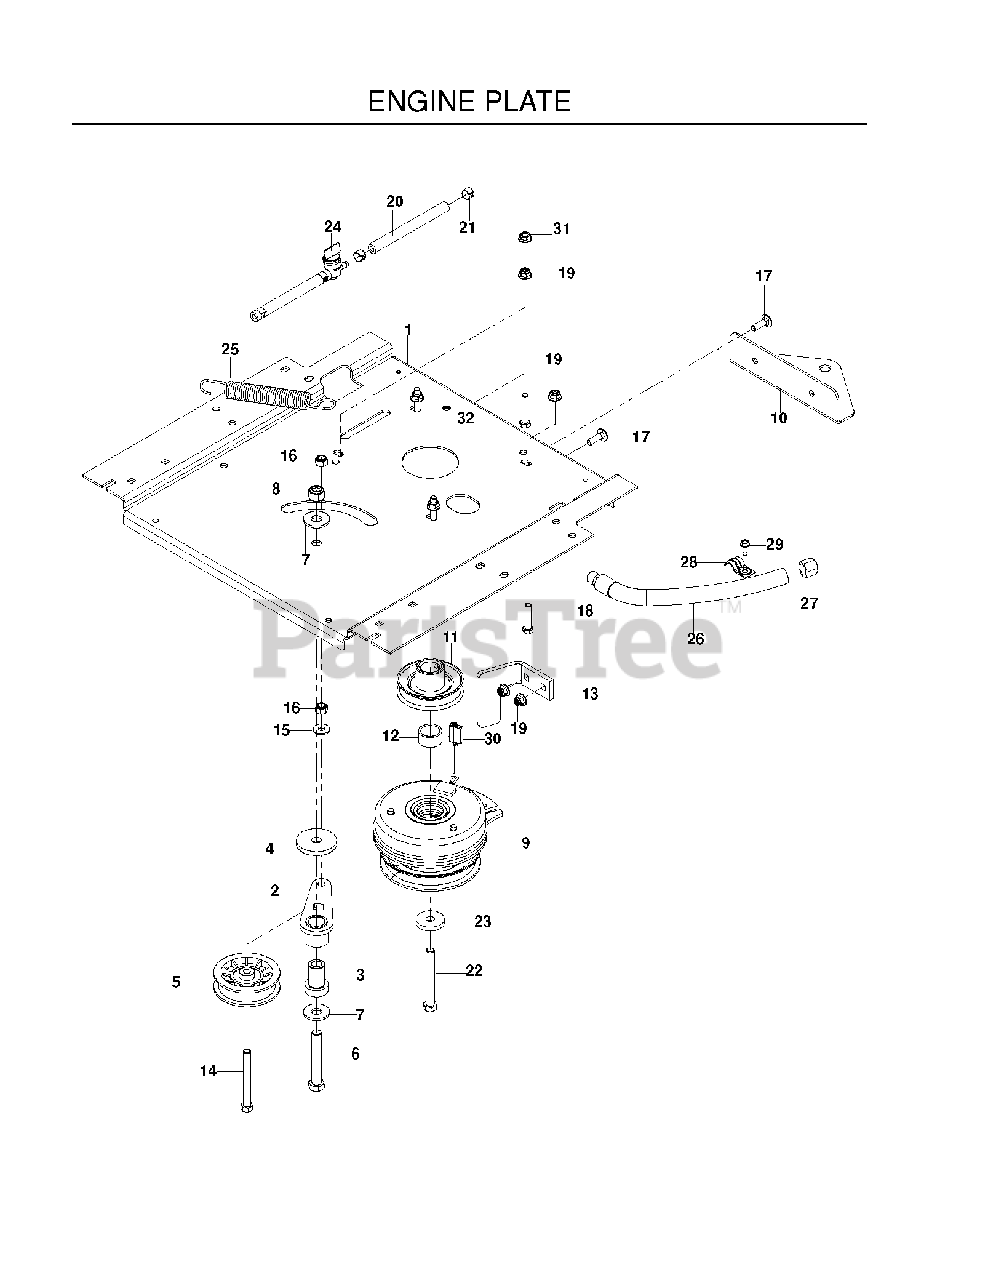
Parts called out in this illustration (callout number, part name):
1	PLATE ENGINE, BLACK
2	IDLER ARM WELDMENT
3	IDLER SPINDLE
4	HEAVY WASHER
5	PULLEY, IDLER RAKE & ZTR
6	HCS 1/2C X 3 1/4
7	WASH USS FLAT 1/2
8	RP NUT 1/2-13 HEX NYLOC ZD
9	CLUTCH, 105 FT-LBS
10	HITCH, BLACK
11	RP PULLEY, ENGINE
12	T & B SPACER
13	STOP, CLUTCH, BLACK
14	HCS 3/8-16X3 1/2 GR5
15	WASHER 5/16 FLAT
16	NUT 3/8-16 NYLOC
17	RHSNB 5/16C X 1
18	CAPSCREW 5/16 X 1/1/2 HEX HEAD
19	5/16-18 NYLOC FLANGE NUT
20	FUEL LINE 5"
21	HOSE CLAMP
22	HCS 7/16-20X3-1/2 GR 5 ZN
23	CLUTCH, WASHER
24	FUEL VALVE
25	SPRING, DECK DRIVE
26	OIL DRAIN HOSE
29	SCREW 1/4 X 5/8
30	CLUTCH HARNESS
31	NUT 5/16C WHIZ
32	HCS 5/16C X 1 3/4
